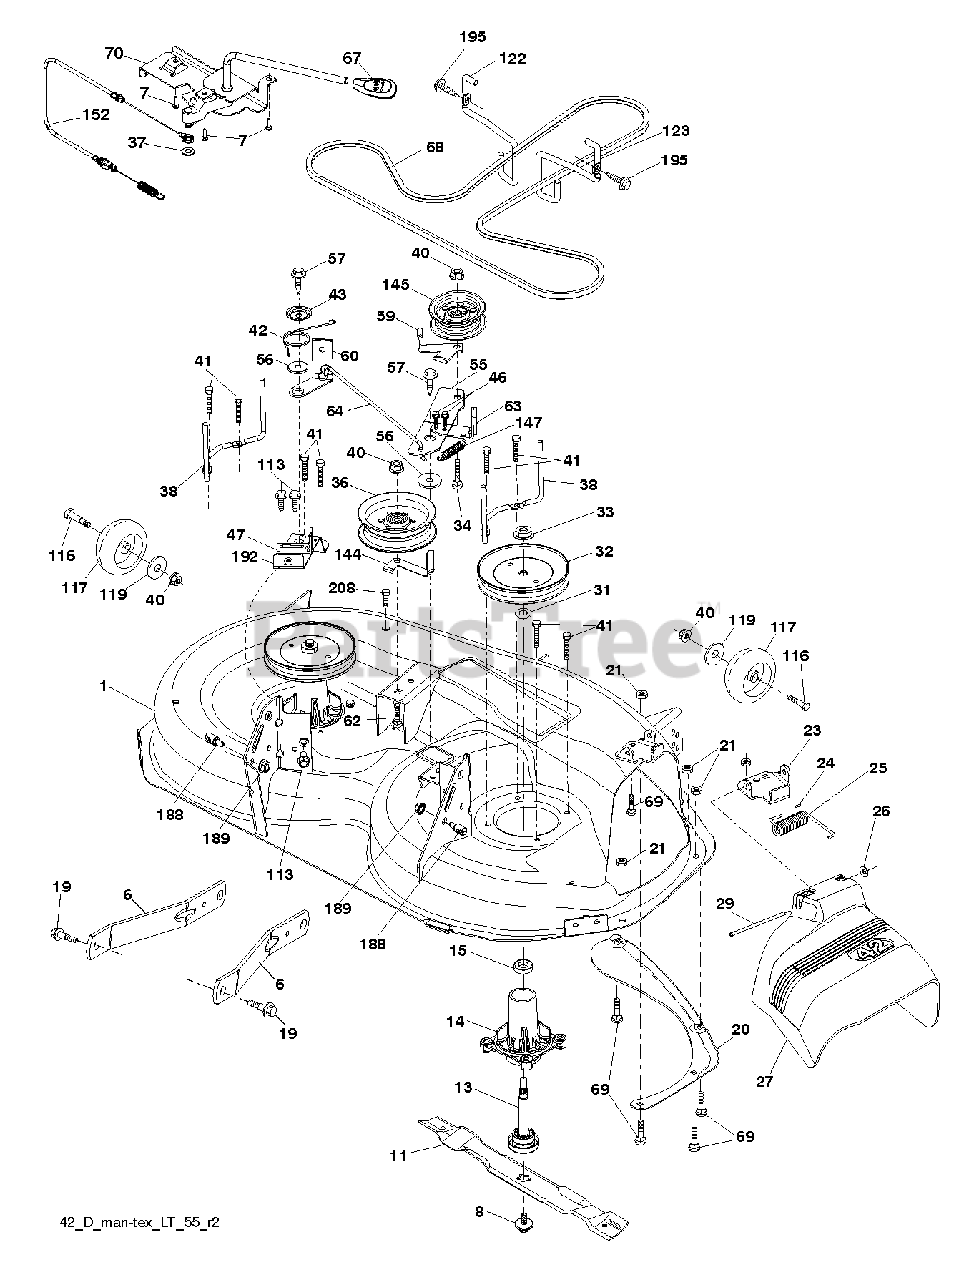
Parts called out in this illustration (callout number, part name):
6	ARM.SUSPENSION.MOWER.R
7	SCREW.#10 X 0.750.BOS (2 2)
8	BOLT.WASHER.ASM.7/16-2
11	42" HI-LIFT BLADE
13	SHAFT.ASM.MDRL.N/GREASE.38
14	HOUSING.MANDREL.4PT.
19	BOLT.SHOULDER
20	BAFFLE.VORTEX
21	LOCKNUT
23	BRKT.DEFLECTOR.38"2005+
24	CAP-SLEEVE LT
25	SPRING.TORSION.DEFLECT
26	NUT PUSH M
27	SHIELD.DEFLECTOR.MOWER.42"BLAC
29	ROD.HINGE
31	WASHER.SPACER.MANDREL
32	PULLEY.MANDREL.5.438.PD
33	NUT.FLANGE.LOCK.TOP
34	BOLT.3/8-16X1.50
36	PULLEY.IDLER.2006
38	KEEPER.BELT.MANDREL.PULLEY
40	NUT LOCK FLG 3/8-16 UNC
41	Hex Washer Head Bolt, .313-18 X 1.19
42	SPRING.TORSION.BRAKE
43	SRPING.TORSION.RETAINE
46	SCREW.1/4-20X5/8
47	BRKT.CLUTCH.CABLE
55	IDLER.ARM.42"
56	SPACER.RETAINER
57	SCREW 3/8-16X1
59	GUARD, BELT
60	ARM BRAKE MOWER
62	BOLT
64	LINK BRAKE
67	HANDLE.CLUTCH.CABLE.LT
68	BELT.DECK.DRIVE.42"
69	BOLT
70	CLUTCH.ASM.MANUAL.LT.TEX
113	BOLT.5/16HEX.WHS.HD
116	BOLT M
117	WHEEL.GAGE.HALF.SPOKED
119	WASHER
122	KEEPER BELT ENGINE LH
123	KEEPER BELT RH
144	KEEPER.BELT.MOWER
145	PULLEY.IDLER.48"PRIMARY
147	RETURN SPRING
152	CABLE.MECHANICAL.CLUTCH
188	STUD.FASTNER.W/ANTI-ROTATE
189	NUT LOCK HEX FLANGE 5/16-18
192	BRKT.BRAKE.STAND.LH.
195	SCREW, 3/8-16X3/4
208	SCREW 3/8-16X1/2
